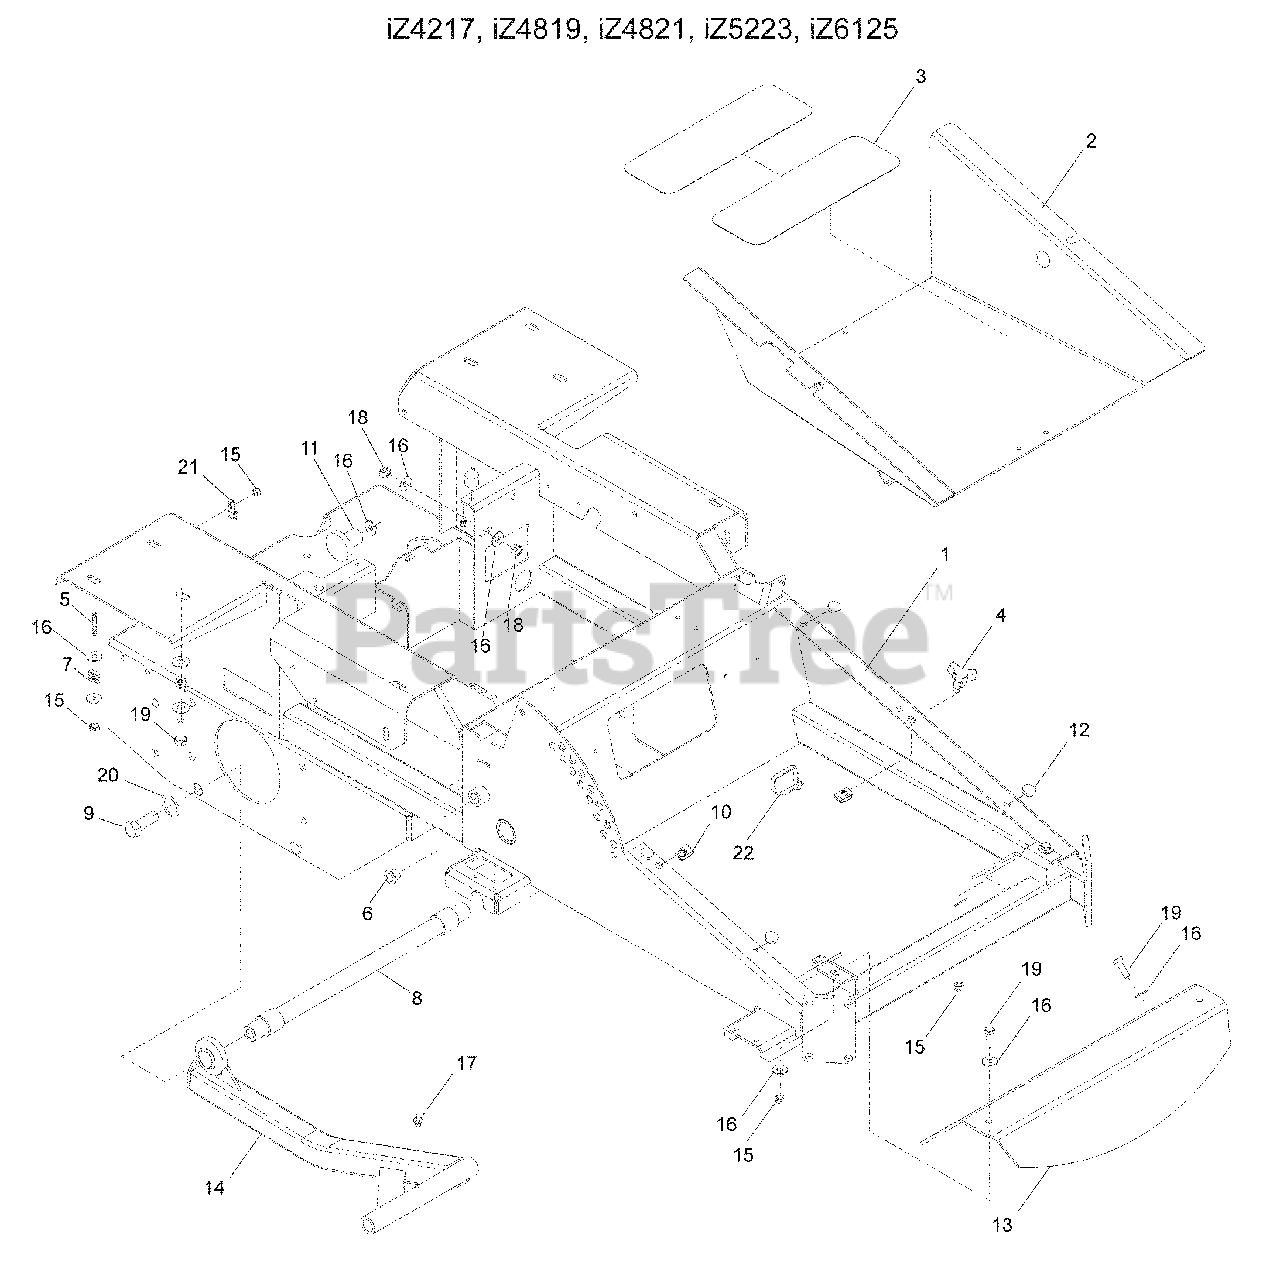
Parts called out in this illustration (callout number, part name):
1	FRAME w/DECALS
2	FOOT PLATE w/DECALS
3	PAD, ABRASIVE
4	KNOB w/STUD
5	TANK-STUD FUEL
7	SPRING, FUEL TANK
8	STRUT MOUNT
9	HCS 5/8-11 x 2
10	NUT 5/16-18, U-TYPE
12	GROMMET, BUMPER
15	NUT 5/16-18 HEX NYLOC
16	WASHER 5/16 STD FLT
17	ZERK, STRAIGHT ¼-28
18	NUT 5/16-18 HEX CTRLK
19	HCS 5/16-18 x 1
20	WASHER 5/8 SPLIT LOCK
21	CLAMP, DOUBLE TUBE
22	TIE, PLASTIC
